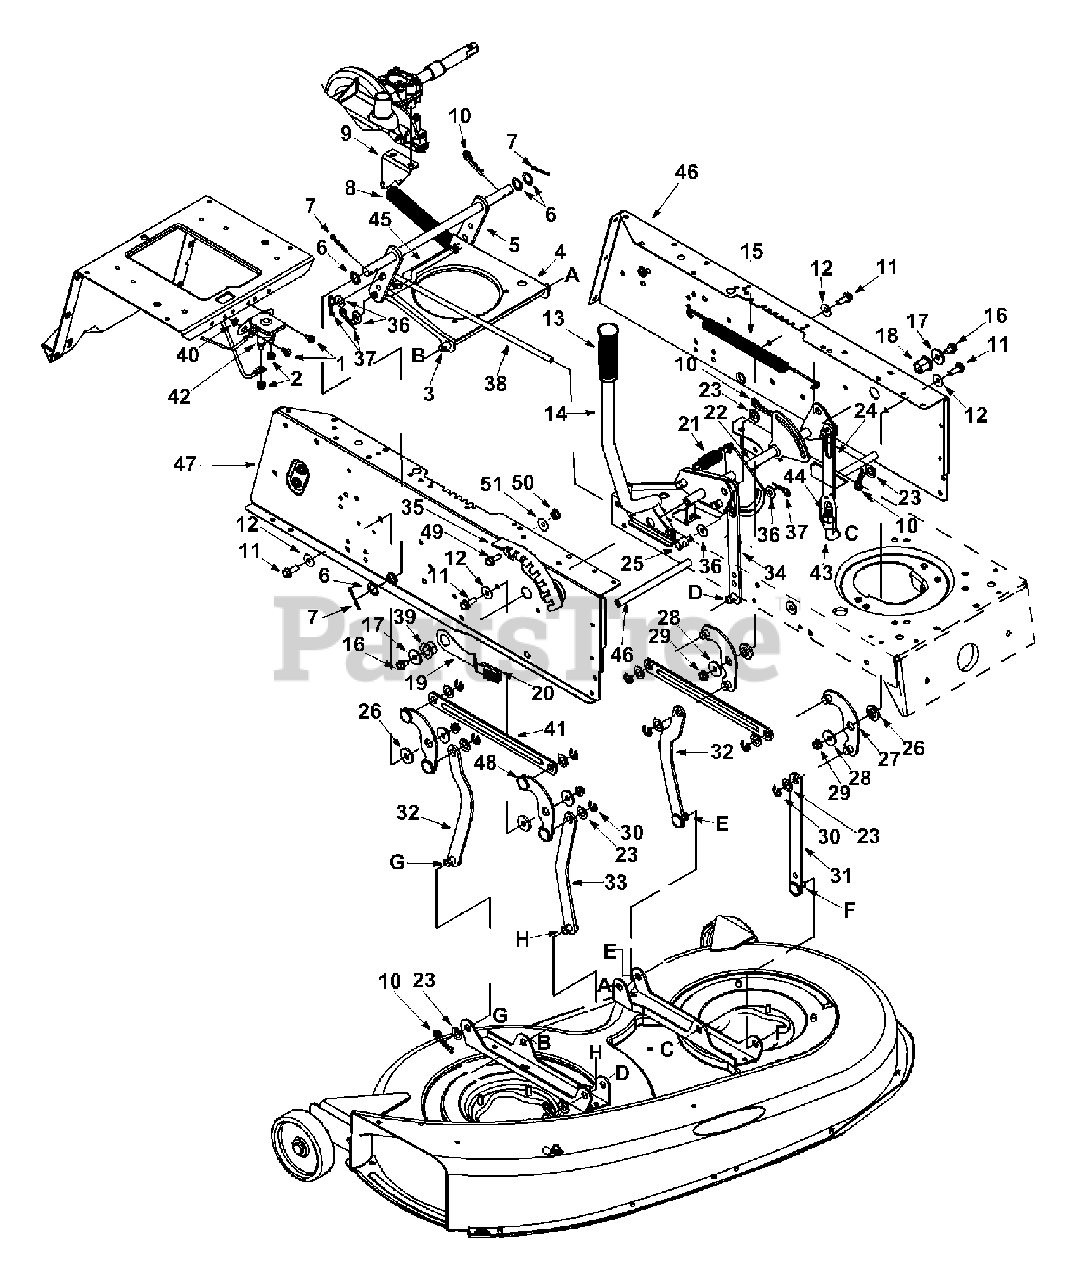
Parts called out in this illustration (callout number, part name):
1	Self Tap Screw 1/4-20 x .50" Lg.
2	Sems Hex Nut 1/4-20
3	Shaft 1/2" Dia. x 10.50" Lg.
6	Fl-Wash. .635 I.D. x .930 I.D.
7	Cotter Pin 1/8" Dia.
8	Extension Spring 7.58" Lg.
10	Cotter Pin
11	TT-Tap Scr. 5/16-18 x .75" Lg.
12	Bell-Wash. .325" I.D.
13	Grip (Lift Handle)
14	Deck Lift Handle Ass'y
15	Extension Spring
16	TT-Tap Scr. 5/16-18 x ..625" Lg.
17	Fl-Wash. .344 I.D. x 1.25 O.D.
18	Flange Bearing .632 I.D.
19	Hgt. Adj. Stop Lever Ass'y
20	Knob
21	Extension Spring
25	Ferrule 3/8-24 x .375 Dia.
26	Shoulder Spacer .318" Dia.
27	Pivot Link Ass'y -L.H.
28	Fl-Wash. .344 I.D. x .125 O.D.
29	Flange L-Nut 5/16-18 Gr. 5
30	"E" Ring
31	Deck Hanger Link Ass'y
36	Fl-Wash.
37	Hairpin Clip
38	Deck Belt Disengagement Rod
39	Flange Bearing .83 I.D. x .62 O.D.
40	L-Wash.
42	Lift Link Adjuster
43	Hex Nut 1/2-20 Thd. (Gr. 5)
44	Shaft 3/8" Dia. x 9.34" Lg.
45	Running Board Rod
49	Hex Bolt 5/16-18 x .75" Lg.
50	Hex Nut 5/16-18 Thd.
51	Lock Washer 5/16" I.D.
